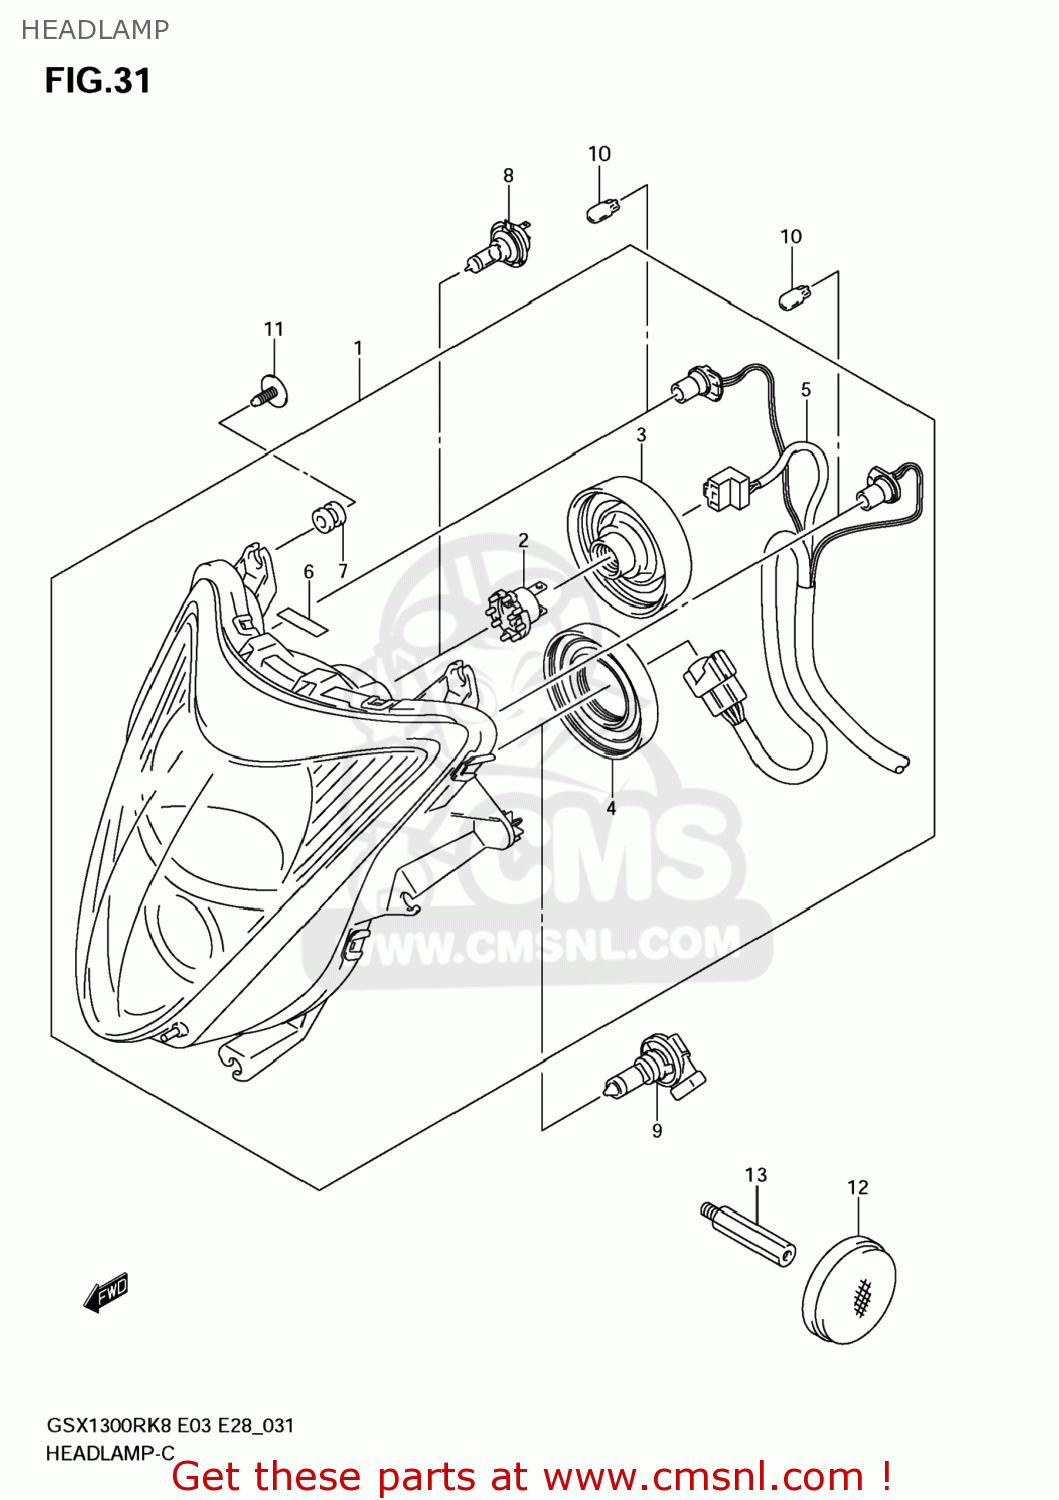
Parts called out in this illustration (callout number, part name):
1	HEADLAMP ASSY
2	ADAPTER ASSY
3	COVER
4	COVER
5	CORD ASSY
6	TAPE,FR TURNSIGNAL
7	CUSHION
8	BULB(12V55W/H7/PX26D/PHILIPS)
9	BULB(12V65W,H9)
10	BULB(12V5W)
11	SCREW(5X15)
12	REFLECTOR,REFLEX
13	BOLT
